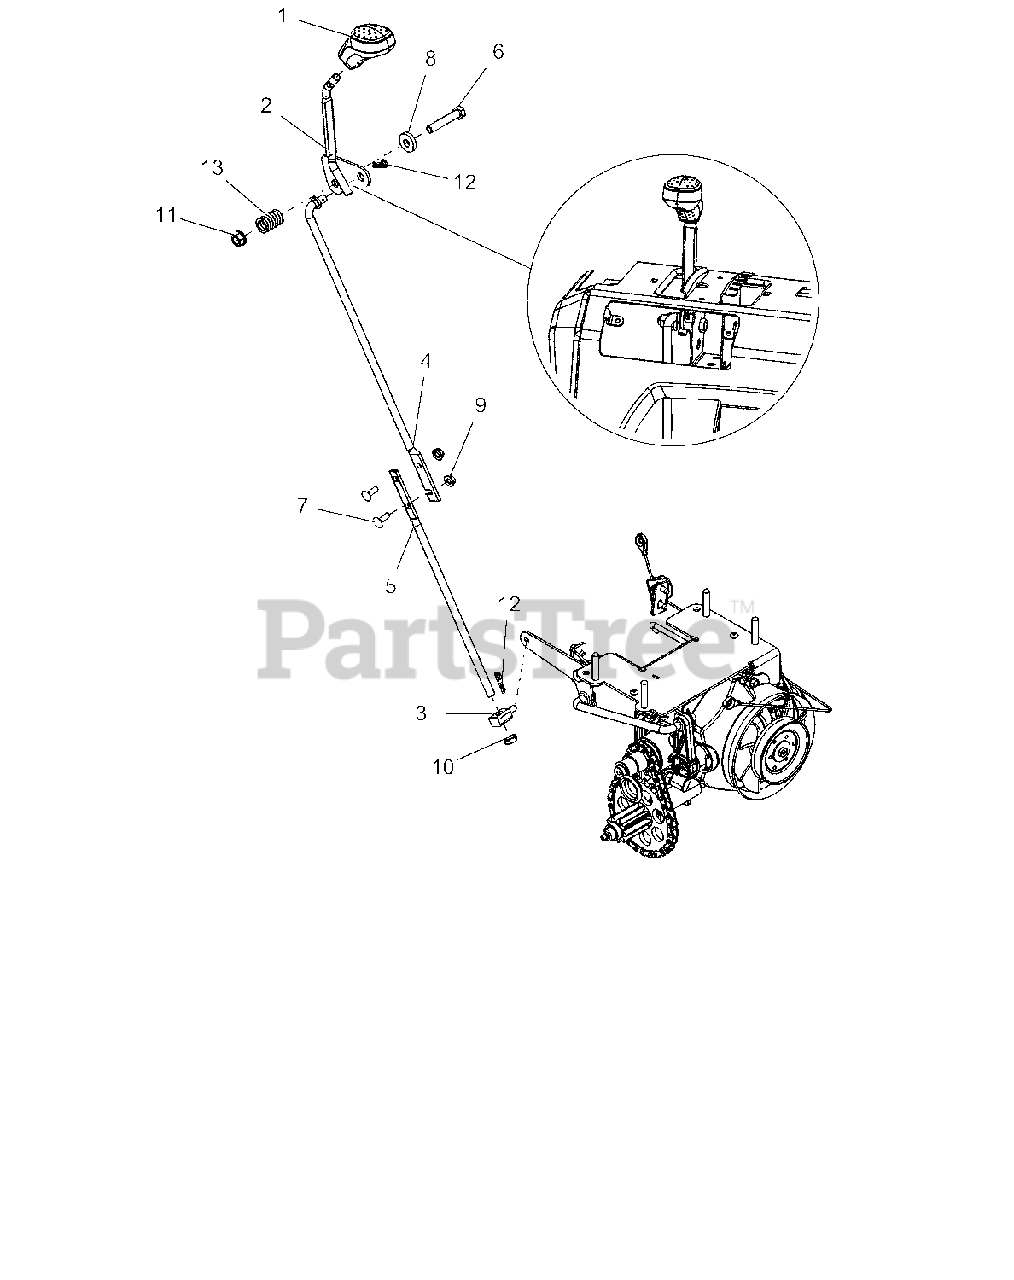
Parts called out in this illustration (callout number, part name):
1	KNOB, CONTROL, DASH
2	WELDMENT,LG DASH SPEED CONTROL
3	PIVOT,SHIFT ROD .375-16(TRUNN)
4	ROD, SHIFT - UPPER
5	ROD. HYDRO SHIFT - LOWER
6	BLT-HEX .38-16X2.00 GR5 YWZC
7	BLT-RDHDSQNK .25-20X.75 G5YZ
8	WSHR-FL-STL .406X1.00X.188 YWZ
9	NUT-LK-CTR-FLG .25-20 YWZC
10	NUT-HEX-JAM .375-16 YWZC
11	NUT-LK-TOP-FLG .38-16 YWZC
12	PIN-HAIR INT .08X.18X1.18 YWZC
13	SG-COMP .125X.781X1.250
